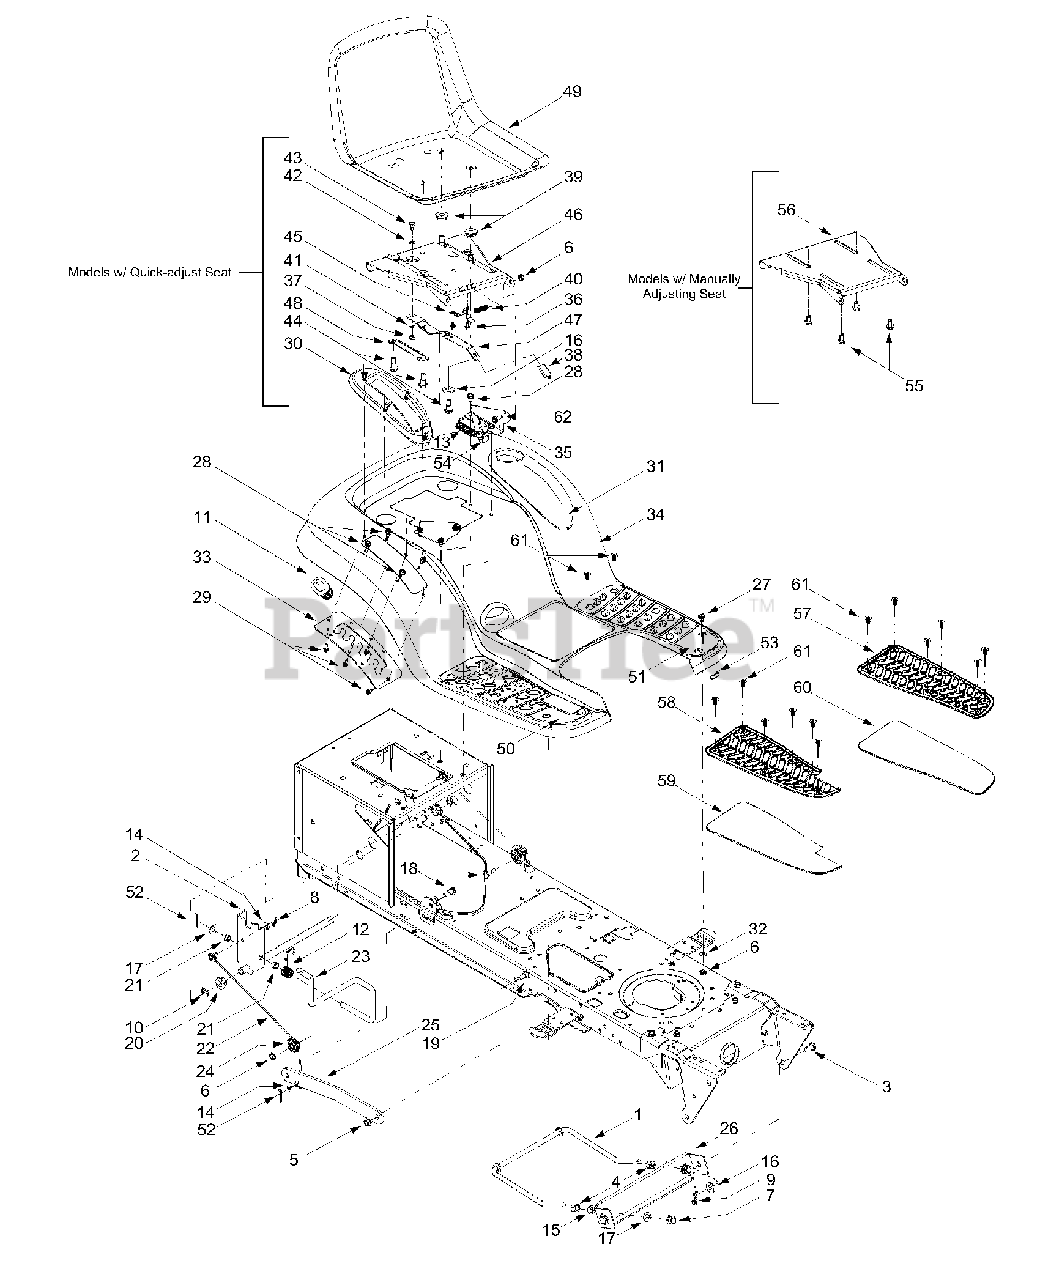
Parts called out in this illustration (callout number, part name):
1	Deck Stabilizer Rod
3	Clevis Pin, .5 x .78
4	Hex Nut, 1/2-13
5	Flange Lock Nut, 3/8-16
6	Flange Lock Nut, 5/16-18
7	Hex Nut, 1/2-13
8	Internal Cotter Pin
9	Internal Cotter Pin
10	E-ring
11	Handle Grip
12	Torsion Spring
13	Extension Spring, .872 x 3.4
14	Flat Washer, 5/16
15	Lock Washer, 1/2
16	Flat Washer, .31 x 1.062 x .134
17	Flat Washer, .51 x 1.12 x .06
18	Hex Cap Screw, 5/16-18 x .62
19	Shoulder Screw, 3/8-16
20	Hex Flange Bearing
21	Snap Flange Bearing
22	Lift Cable, 16.16
23	Lift Handle
24	Roller Pulley
27	Carriage Bolt, 5/16 x .62
28	Self-tapping Screw, 5/16-18 x .625
29	Self-tapping Screw, 1/4-15 x .75
30	Lift Lever Cover
31	Cover w/ Cup Holder
32	Flat Washer, .349 x 1.0 x .063
36	Screw, #10-16 x .375
37	Hex Flange Lock Nut, 1/4-20
38	Seat Adjuster Grip
39	Spacer
40	Compression Spring, .41 x 1.5
41	Spring Washer, .265 x .562 x .025
42	Flat Washer, .344 x .62 x .03
43	Shoulder Screw, .340 x .285,1/4-20
44	Shoulder Screw, .50 x .50, 3/8-16
45	Seat Stop
48	Seat Adjustment Selector
49	High Back Seat, Black
49	High Back Seat w/ Drain Holes, Black
49	Medium Back Seat, Black
50	RH Foot Pad, Rubber (4-Style Fender)
51	LH Foot Pad, Rubber (4-Style Fender)
52	Cotter Pin
53	Trim Strip
54	Seat Lift Bracket
55	Hex Head Washer Screw, 3/8-16 x .625
58	LH Foot Pad, Rubber (7-Style Fender)
59	RH Foot Pad, Grit (7-Style Fender)
60	LH Foot Pad, Grit (7-Style Fender)
61	Ratchet Clip
62	Shoulder Screw, .437 x .286
